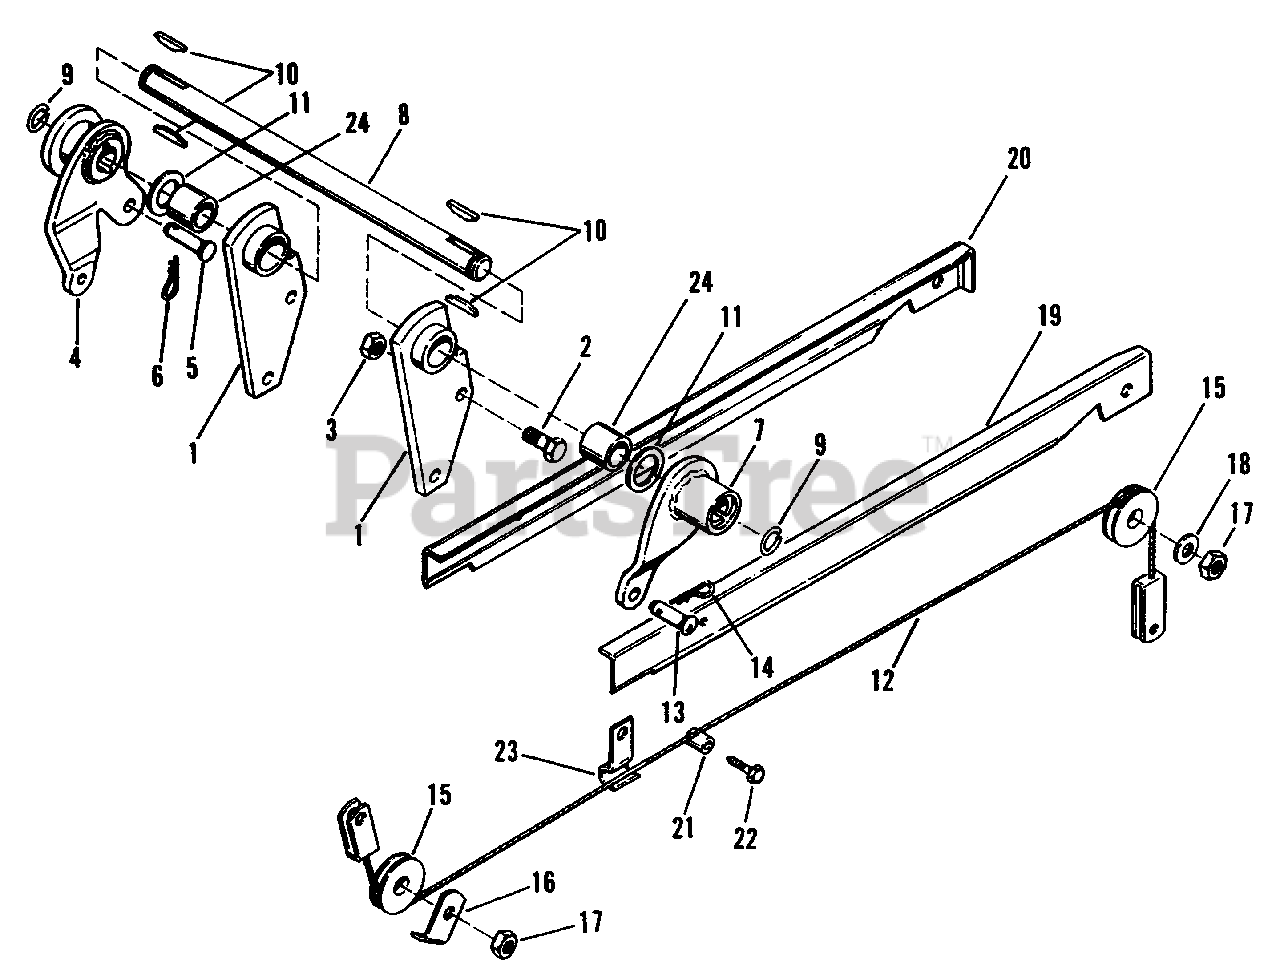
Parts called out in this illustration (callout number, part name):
1	Support Assembly
2	Hex Capscrew, 1/2-13 x 1-1/2" lg.
4	Lift Arm Assembly, L.H.
6	Hair Pin Clip
7	Lift Arm Assembly, R.H.
8	Rock Shaft
9	Retaining Ring
12	Cable Assembly
14	Spring Clip
16	Wire Guide
17	Lock Nut, 1/2"-13
18	Plain Washer
19	Wire Guide, R.H.
20	Wire Guide, L.H.
22	Self Tapping Screw, 1/4"-20 x 1 1/4" lg.
23	Wire Guide
